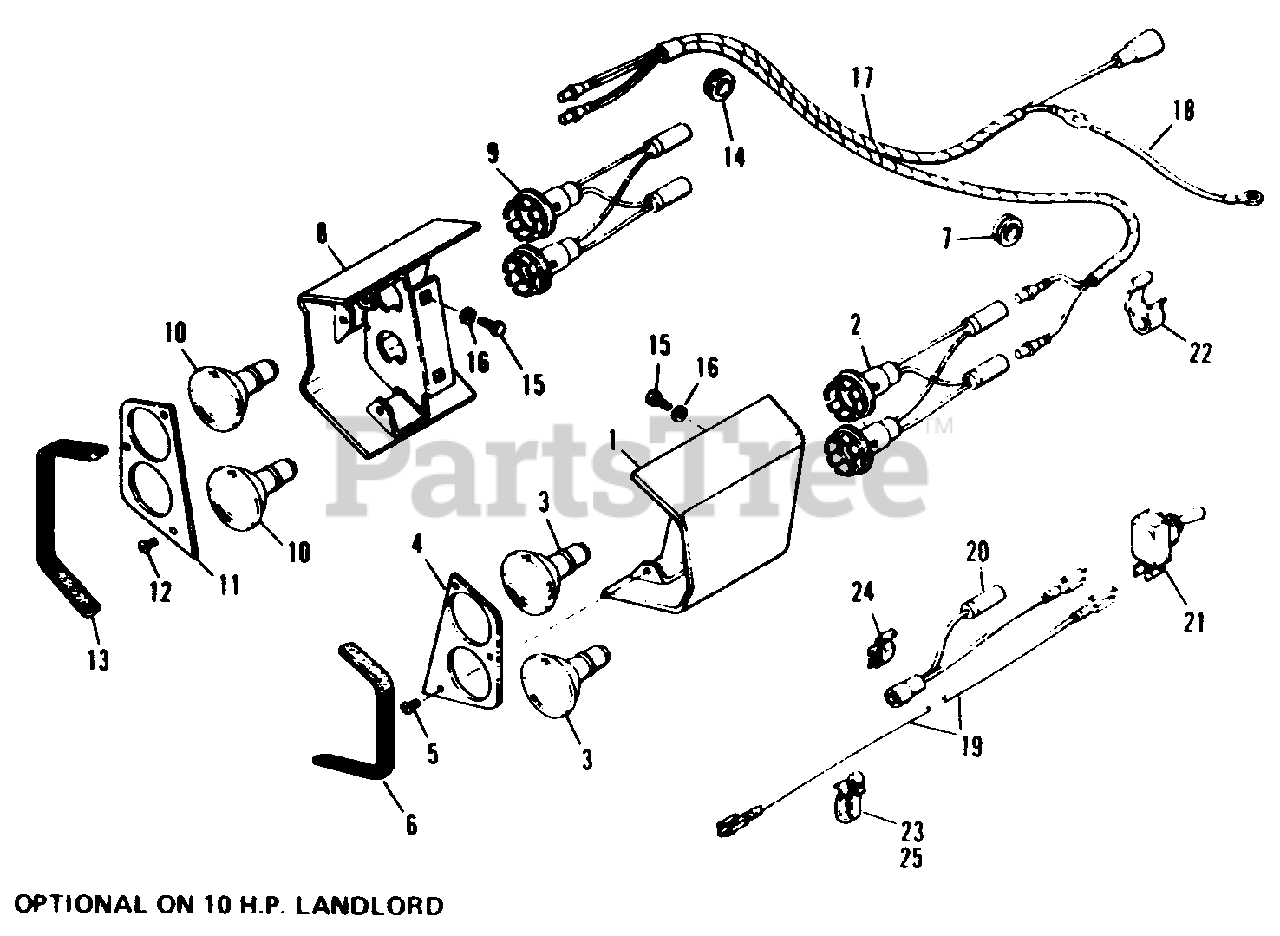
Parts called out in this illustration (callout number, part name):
1	Shroud & Plate Assy. L.H.
2	Lamp Socket & Wire Assy.
3	Headlight
4	Plate, Front
5	Screw, Round Head Phillips Swageform No. 12-24 x 1/2"
8	Shroud & Plate Assy. R.H.
9	Lamp Socket & Wire Assy.
10	Headlight
11	Plate, Front
12	Screw, Round Head, Phillips Swageform No. 12-24 x 1/2"
15	Hex Cap Screw, 1/4"-20 N.C. x 1/2"
16	Lock Washer, 1/4" Std.
17	Harness Assy.
18	Wire Assy., Ground
19	Wire Assy., Light Switch
20	Wire Assy., Indicator Lamp
21	Switch, Toggle
22	Cable Clip Tinnerman, Front Frame
23	Cable Clip Tinnerman, Rear Frame
24	Cable Clip Tinnerman, Top of Grille
25	Cable Clip Tinnerman
